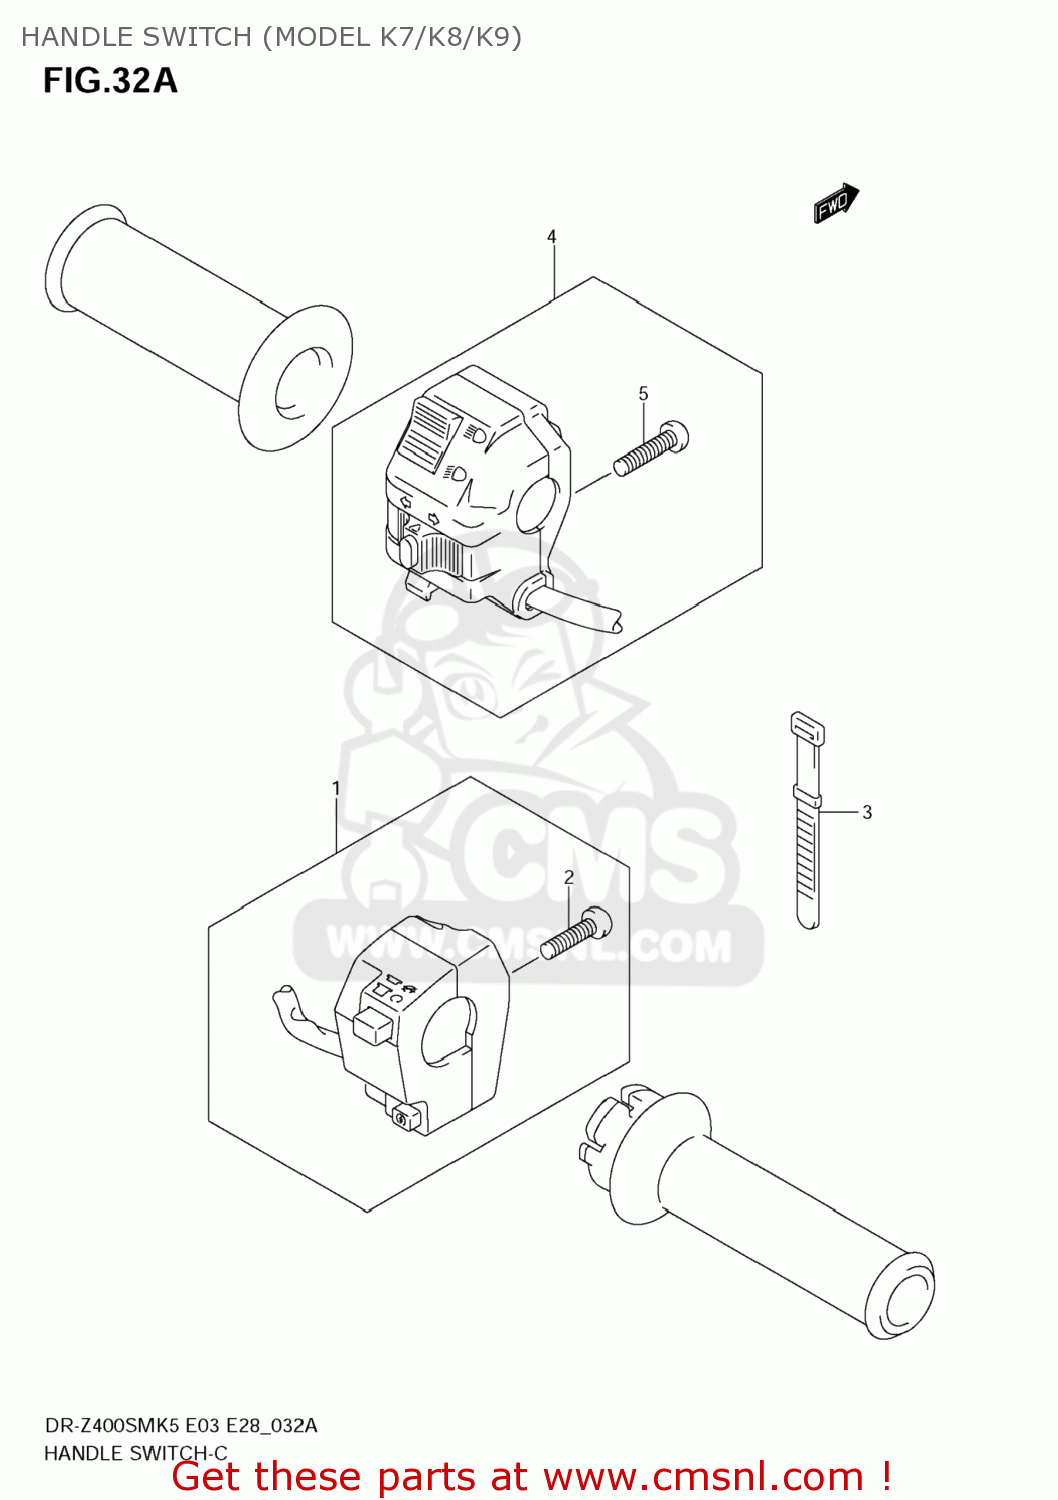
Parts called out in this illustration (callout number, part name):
1	SCHAKELAAR RH
2	SCREW
3	CLAMP(L:120)
4	SWITCH ASSY,HANDLE,L
5	SCREW
